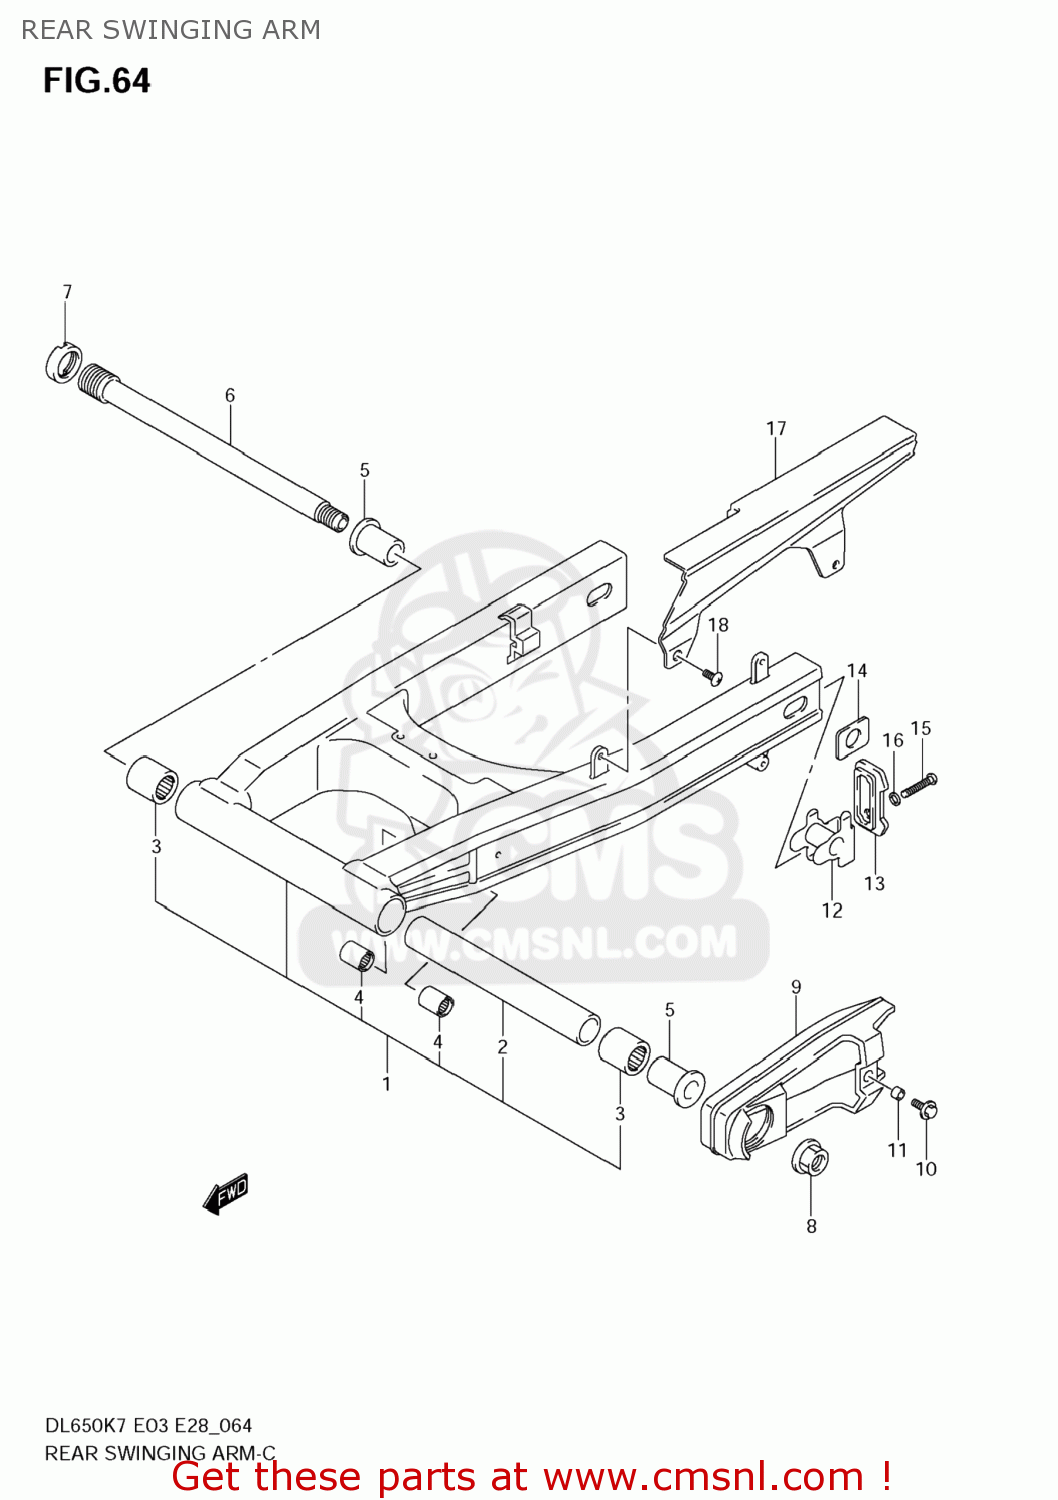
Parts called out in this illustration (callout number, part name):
1	SWINGINGARM AS
2	SPACER(20.8X27.2X196.7)
3	BEARING(25X33X35)
4	BEARING(17X24X25)
5	SPACER,RR SWGARM PIVOT BERRING
6	SHAFT,RR SWINGINGARM PIVOT
7	NUT,REAR SWING ARM PIVOT BOLT
8	NUT
9	BUFFER,CHAIN TOUCH DEFENSE
10	BOLT(6X20)
11	SPACER(6.5X10X7)
12	ADJUSTER,CHAIN
13	PLATE,CHAIN ADJUSTER GUIDE,R
14	WASHER,CHAIN ADJUSTER
15	BOLT(8X50)
16	WASHER
17	CASE,CHAIN
18	SCREW(6X16)
